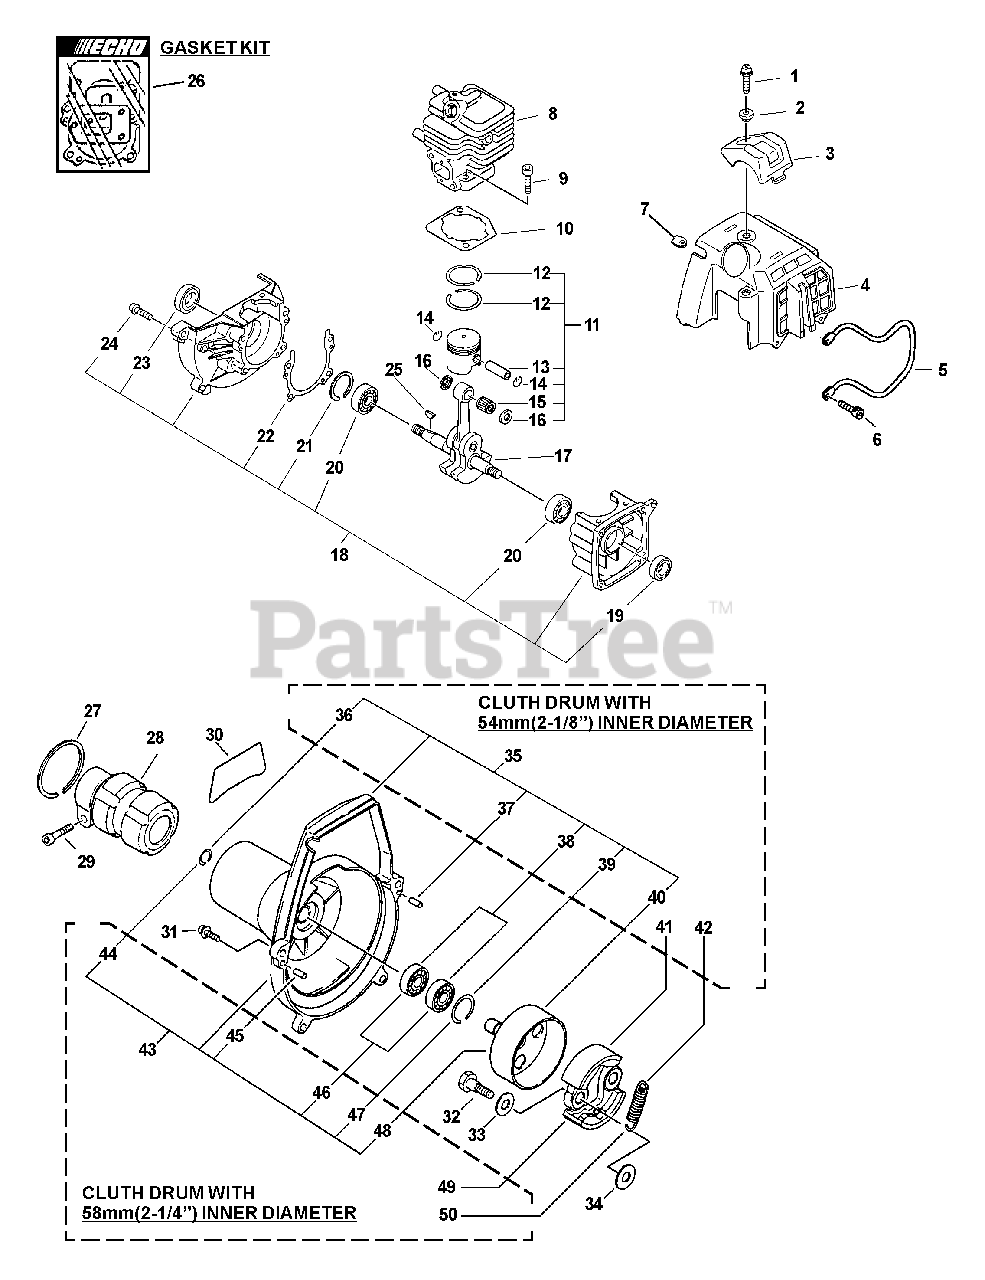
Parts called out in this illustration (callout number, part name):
1	SCREW - 5X22
2	COLLAR - 5
3	GUARD - TOP
4	COVER, ENGINE
5	GUARD, ENGINE
6	SCREW - 4X16
8	CYLINDER
9	SCREW - 5X22
10	GASKET, CYLINDER
11	PISTON KIT
12	RING, PISTON
13	PIN, PISTON
14	RING, RETAINING
15	BEARING, NEEDLE
16	SPACER, PISTON
17	CRANKSHAFT ASSY
18	CRANKCASE KIT
19	SEAL, OIL
20	BEARING, BALL - 6001C3
21	RING, RETAINING - 28
22	GASKET, CRANKCASE
23	SEAL, OIL - 12
24	SCREW - 5X25
26	GASKET KIT
27	RING, RETAINING - 42
28	CLAMP, MAIN PIPE
29	SCREW - 5X28
30	LABEL - MODEL PAS-2601
31	SCREW - 5X18
32	BOLT, CLUTCH
33	WASHER - SPRING
34	WASHER - 6
35	FAN CASE ASSY
36	RING, RETAINING - 12
37	PIN - LOCATING
38	BEARING, BALL - 6001
39	RING, RETAINING - 28
40	DRUM, CLUTCH
41	SHOE, CLUTCH
42	SPRING, CLUTCH
43	FAN CASE ASSY
44	RING, RETAINING - 12
45	PIN - LOCATING
46	BEARING, BALL - 6001
47	RING, RETAINING - 28
48	DRUM, CLUTCH
49	SHOE, CLUTCH
50	SPRING, CLUTCH
